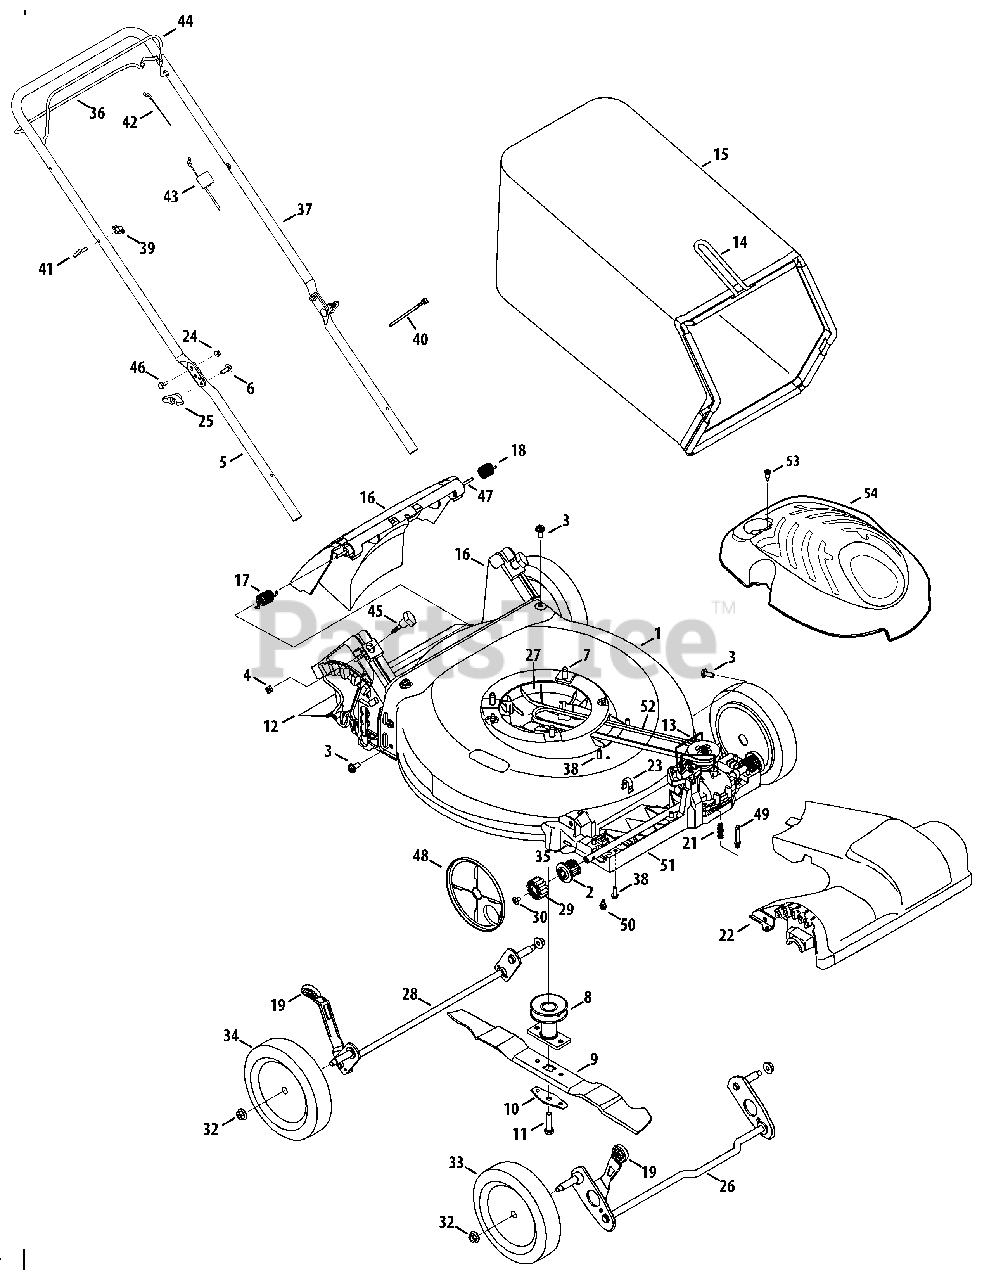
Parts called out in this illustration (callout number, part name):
1	Deck , 21" - Red
1	Deck , 21" - Green
2	Bearing Assembly
3	Screw, 5/16-14 x .750
4	Nut, Sq., 1/4-20
5	Lower Handle
6	Carriage Screw ,5/16-18
7	Screw, 3/8-16 x 1.00
8	Blade Adapter
9	Mulching Blade
10	Blade Bell Support
11	Screw, 3/8-24 x 1.50
12	Trailing Shield
13	Transmission Wire
15	Grass Bag
15	Grass Bag (Yardman)
16	Rear Discharge Door Assembly
16	Rear Door Assembly (Briggs)
17	Torsion Spring - RH
18	Torsion Spring - LH
19	Adjustment Lever Knob
20	Screw, 1/4-20 x .500
21	Compression Spring
22	Front Cover
23	Front Axle Clip
24	Nut, Flange Lock, 1/4-20
25	Wing Knob
26	Front Axle Assembly
27	Engine Baffle
28	Rear Axle Assembly
29	Spur Gear, 14T - RH
29	Spur Gear, 14T - LH
30	Screw, 1/4-20 x .390
32	Flange Lock Nut, 3/8-16
33	Front Wheel
34	Rear Wheel
35	Dowel Pin
36	Drive Control
37	Upper Handle
38	Screw, 1/4-15 x .750
40	Cable Tie
41	Rope Guide
42	Control Cable 50.56" Lg
42	Control Cable (Briggs) 37.75" Lg
43	Drive Cable
44	Blade Control
45	Wing Nut
46	Sldr. Screw, .375 x .126 x 1/4-20
47	Pivot Rod
48	Wheel Dust Cover
49	Spring Body
50	Screw., Shldr., 1/4-20 x .50
51	Lower Tray
53	Screw, #12-16 x 1.00
54	Engine Shroud
